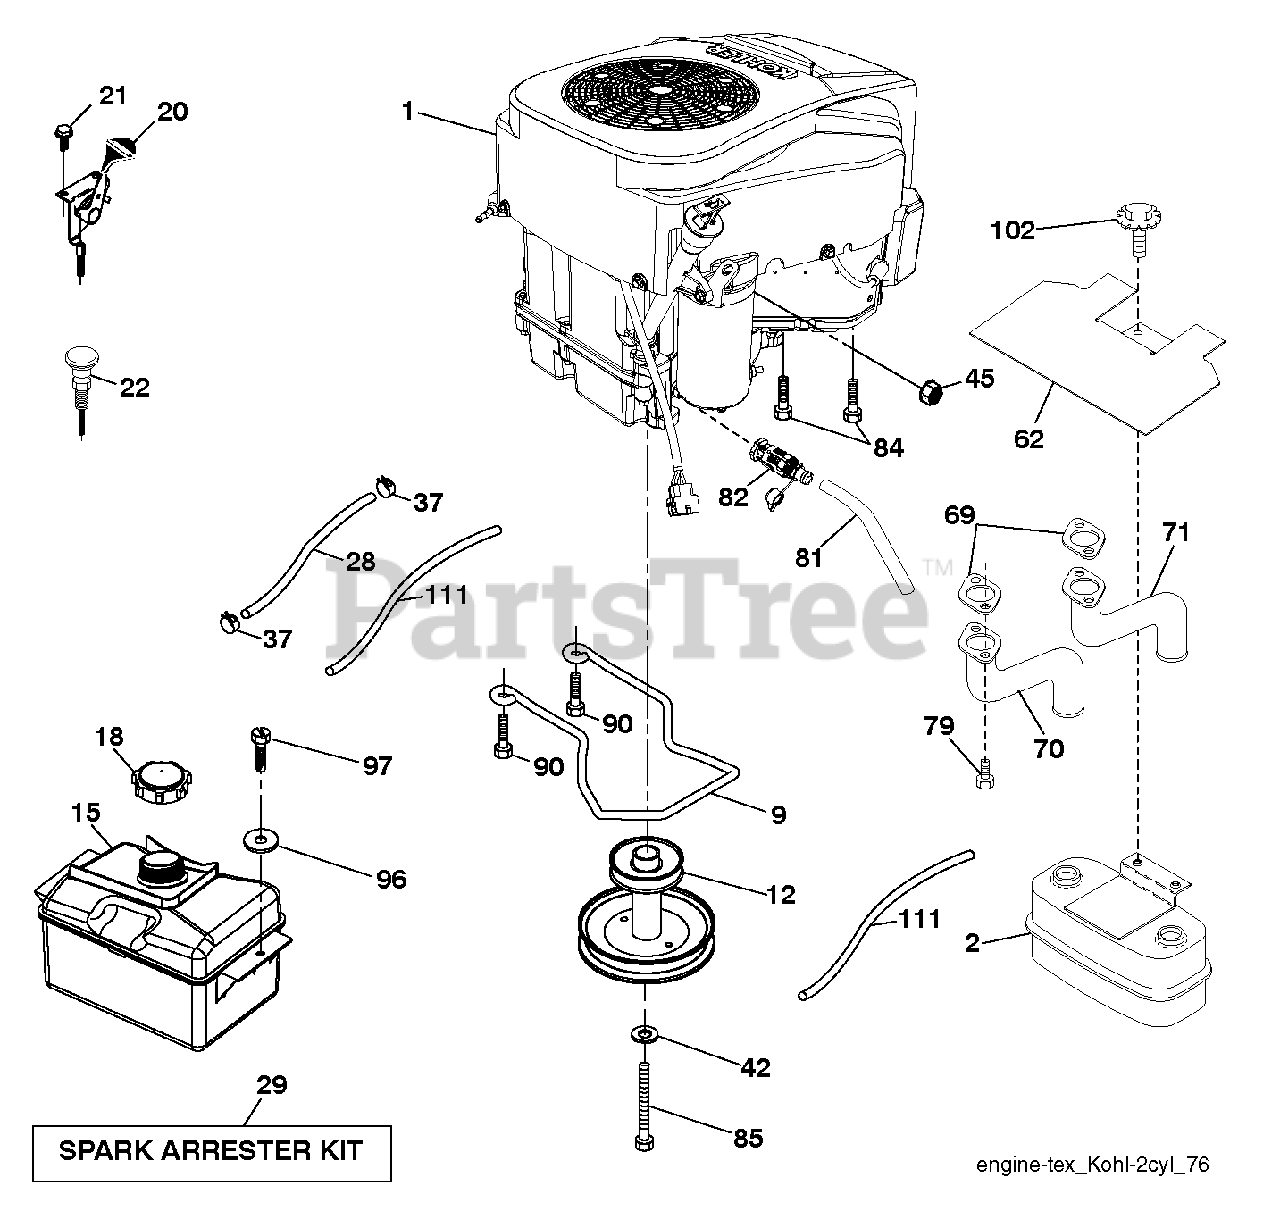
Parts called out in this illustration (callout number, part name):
2	Muffler Assembly, Twin MN
9	KEEPER.BELT.ENG.4.25"2.BLT.431
12	PULLEY.ENGINE
15	Front Tank Assembly, 2.5 Gallon
18	CAP.2.25'.VENTED.TETHER .EPA
20	THROTTLE CONTROL
21	SCREW.#10 X 0.750.BOS
22	CONTROL.CHOKE.ERGO.PUSH-IN.BLA
28	Fuel Hose, 1/4" Low Perm
29	KIT.SPARK ARRESTOR 794945 B&S
37	HOSE CLAMP
42	WASHER 7/16 LOCK
45	NUT
62	SHIELD.HEAT.MUFFLER
69	GASKET.EXHAUST.KOHL.CV18-CV26
70	TUBE.EXHAUST.RH.FR961/FR730
71	PIPE.EXHAUST.RH.CV18/20
79	SCREW.SOCKET HD.5/16-1
81	TUBE, DRAIN OIL ASM.
82	VALUE.OIL.DRAIN
84	SCREW 3/8-16X1
85	BOLT.HEX.7/16-20X4.GR5.1.5BLUE
90	SCREW 3/8-16X1
97	SCREW HEXWSHR 1/4-20X3/4
102	SCREW
111	RP PURGE LINE
